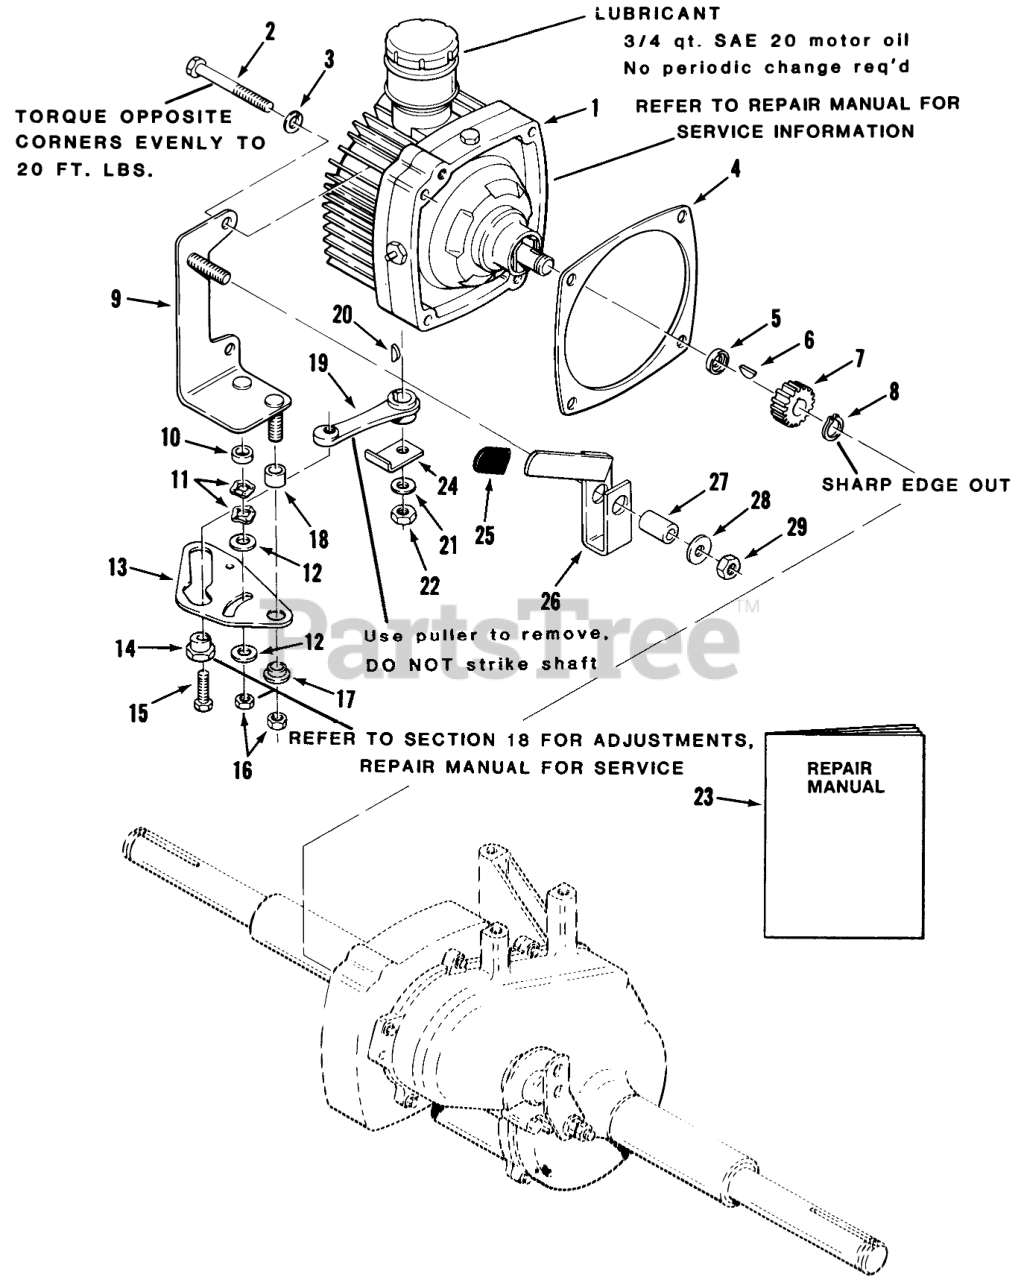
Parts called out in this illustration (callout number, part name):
1	Pump & Motor (219024-Rebuilt)
2	Screw-Hex. Hd.
3	LOCKWASHER
4	GASKET HYDRO
5	SPACER-GEAR
6	KEY WOODR 1/8X1/2 DI
7	Gear 12 Tooth
8	SNAP RING
9	Control Plate
10	SPACER-FRICTION
11	WASHER-SPRING DISC
12	FRICTION WASHER
13	CAM-SPEED CONTROL (NS)
15	Bolt
17	CAM-SPACER
18	SPACER-PIVOT
19	ARM-SPEED CONTROL
20	KEY WOODR 1/8X1/2 DI
21	Washer
22	Nut
23	Automatic Trans. Repair Parts & Service Manual
24	STOP-CAM
25	GRIP
26	ASS'Y-DUMP VALVE B
27	SPACER
28	Washer
29	NUT-HEX, JAM
